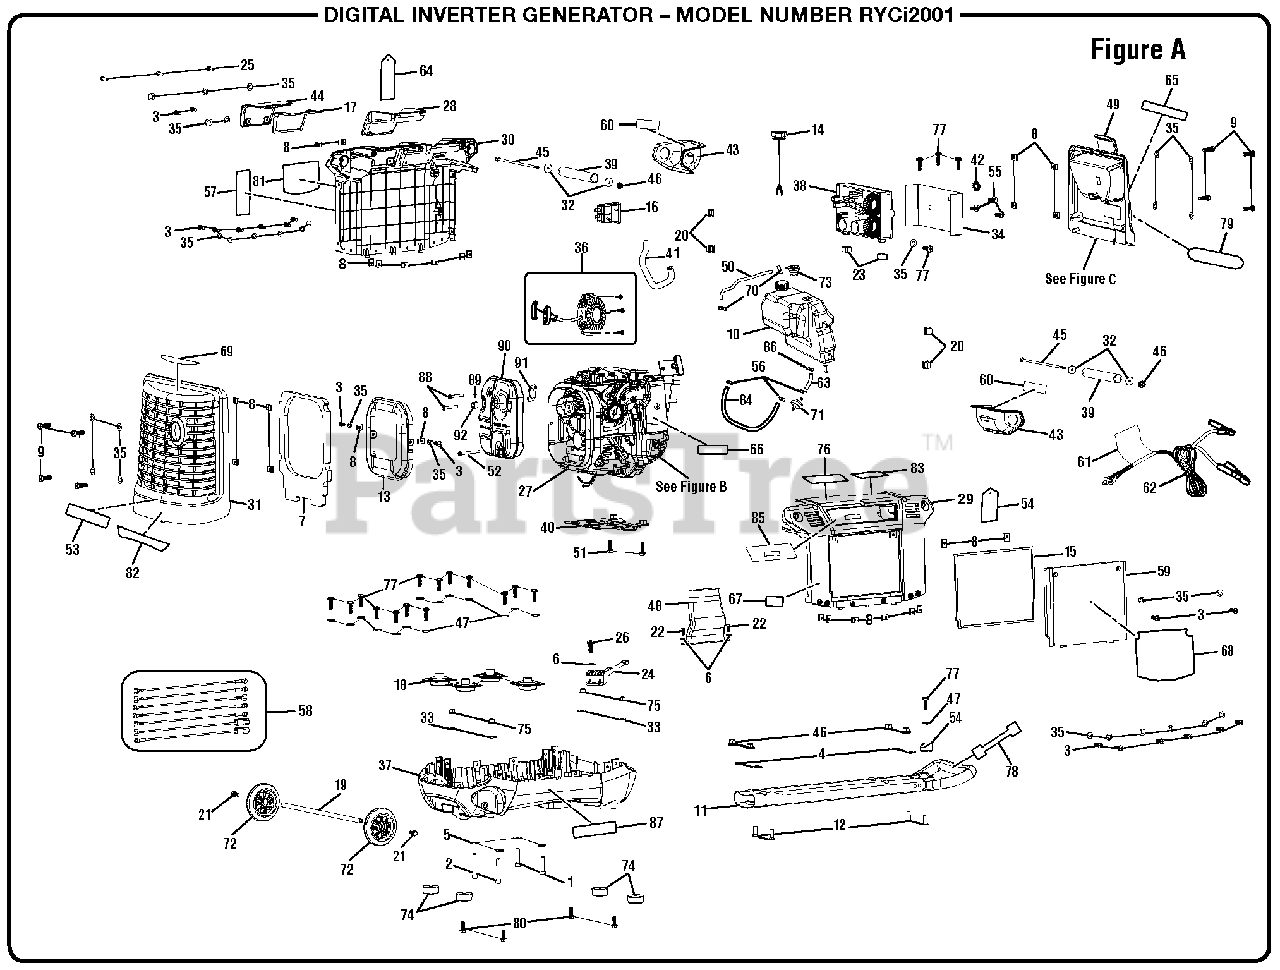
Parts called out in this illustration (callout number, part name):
1	Bolt (M8 x 35 mm, Hex Hd)
2	Bolt (M8 x 50 mm, Hex Hd)
3	Screw (M5 x 12 mm, Phillips Pan Hd)
4	Washer (ID53 x OD15 x 1t)
5	Washer (ID83 x OD16 x 2t)
6	Washer (ID42 x OD10 x 1t )
7	Foam Pad (Isolator)
8	U-Clip (M5 x 08 in)
9	Screw (M5 x 15 mm, Phillips Pan Hd)
10	Fuel Tank
11	Handle Assembly
12	Screw (M5 x 08 in, Phillips Flat Hd)
13	Muffler Noise Cover
14	Fuel Tank Cap
15	Seal (Maintenance Cover)
16	Carbon Canister
17	Spark Plug Cover (Foam)
18	Engine Bracket (Isolator)
19	Wheel Axle
20	Support (Fuel Tank)
21	Screw (M6 x 20 mm, Hex Button Hd)
22	Screw (M35 x 9 mm, Phillips Flange Hd)
23	Base Support
24	Bridge Rectifier
25	Screw (M5 x 19 mm, Phillips Button Hd)
26	Screw (M4 x 10 mm, Phillips Pan Hd)
27	Engine (105cc Top Sun)
28	Fuel Over Spill Guard
29	Left Side Housing
30	Right Side Housing
31	Muffler Cover
32	Washer (ID63 x OD25 x 15t)
33	Washer (ID63 x OD18 x 15t)
34	Air Guide Sheet
35	Washer (ID53 x OD10 x05t)
36	Recoil Starter Assembly
38	Inverter Module
39	Handle (Upper)
40	Engine Bracket Assembly
41	Air Hose (Carbon Canister To Air Box)
42	Star Washer
43	Handle Cover
44	Access Cover (Spark Plug)
45	Bolt (M5 x 175 mm, Hex Hd)
46	Flange Nut (M5 x 08 in)
47	Washer (ID53 x OD10 x 1t)
48	Air Filter Duct
49	Control Panel Assembly
50	Air Hose (Fuel Tank)
51	Bolt (M8 x 30 mm, Hex Hd.)
52	Bolt (M6 x 65 mm, Flange Hex Hd.)
53	Combustion Label
54	Handle Bumper
55	Bolt (M6 x 12 mm, Hex Hd.)
56	Clamp (D9.5 mm)
57	Danger Icon Label
58	Internal Wire Assembly
59	Maintenance Cover
60	Warning Transport w/Handle Label
61	Cord Label
62	DC Cable Assembly
63	Fuel Hose (50 mm)
64	Danger Hangtag
65	Logo Label (Small)
66	Maintenance Label
67	Check Oil Label
68	Logo Label (Large)
69	Hot Surface Label
70	Clamp (D7 x 0.8 mm)
71	Fuel Filter (1/4 in.)
73	Rollover Vent
74	Rubber Foot w/Metal Insert
75	Nut (M6 x 1 mm )
76	CPSC Label
77	Screw (M4.2 x 12mm, Phillips Button Hd.)
78	Handle Release Label
79	Ground Warning Label
80	Bolt (M6 x 16 mm, Hex Hd.)
81	Performance Label
82	Fire Distance Label
83	E85 Label
84	Fuel Hose (Fuel Tank To Fuel Pump)
85	Quick Start Label
86	Clamp (10 mm)
87	Data Label (2014)
88	Bolt (M6 x 45 mm, Flange Hex Hd.)
89	Screw (M4.2 x 8 mm, Pan Hd.)
91	Exhaust Pipe Gasket
92	Spark Arrestor
